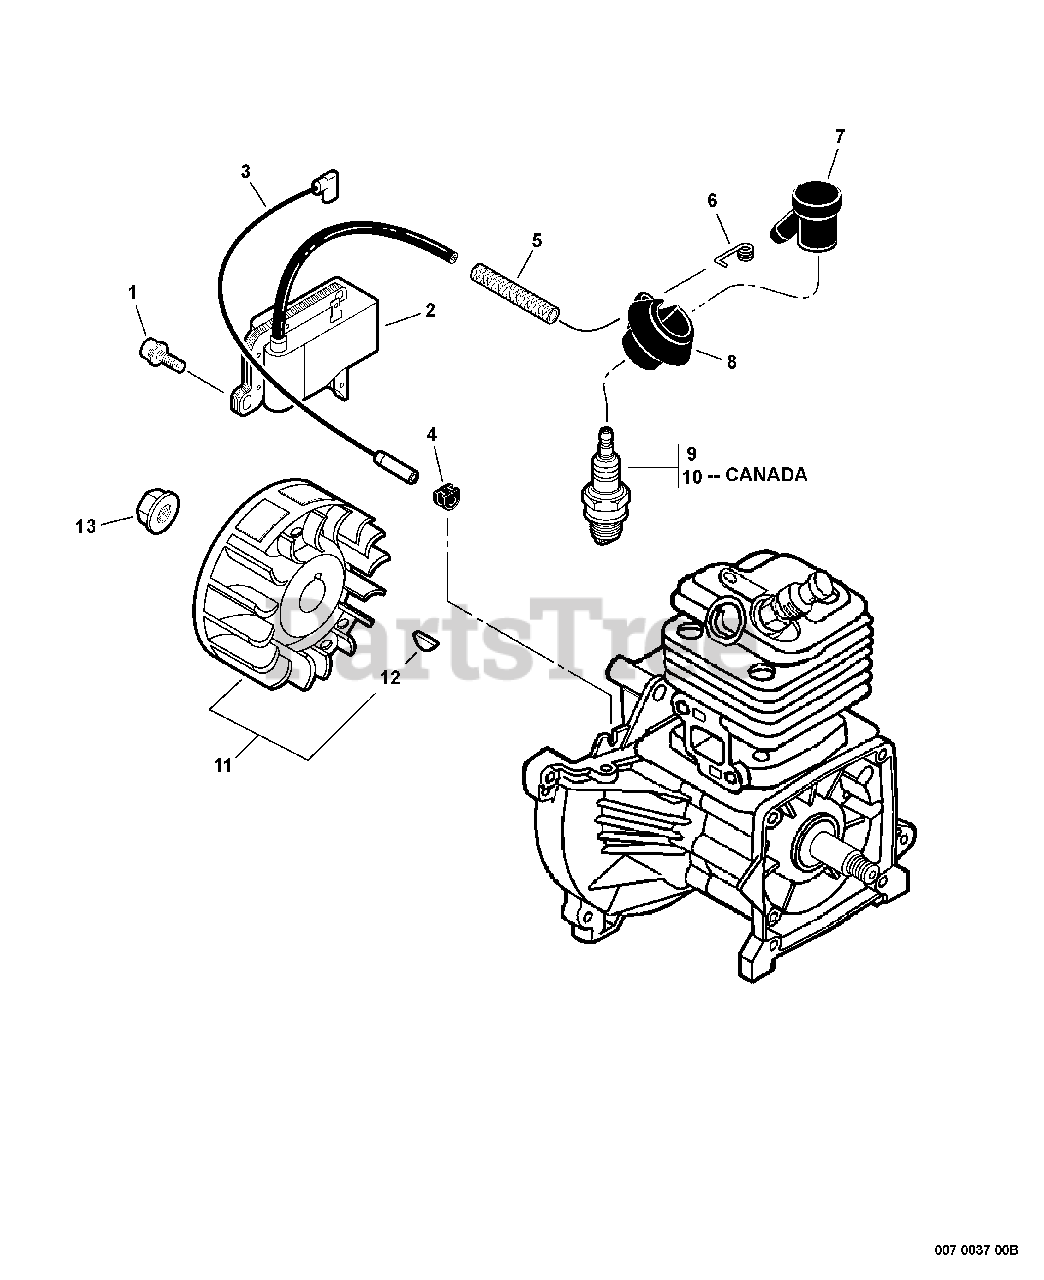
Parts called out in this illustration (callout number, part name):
1	BOLT 5×20
2	COIL, IGNITION
3	LEAD 170 MM
5	TUBE, INSULATOR 7×8.6×55
6	TERMINAL, SPARK PLUG
7	CAP, SPARK PLUG
8	COVER, DUST
9	SPARK PLUG - BPM7A
10	SPARK PLUG - BPMR7A
11	FLYWHEEL KIT
12	KEY, WOODRUFF 3×14
13	NUT, FLANGE 10×1.25
